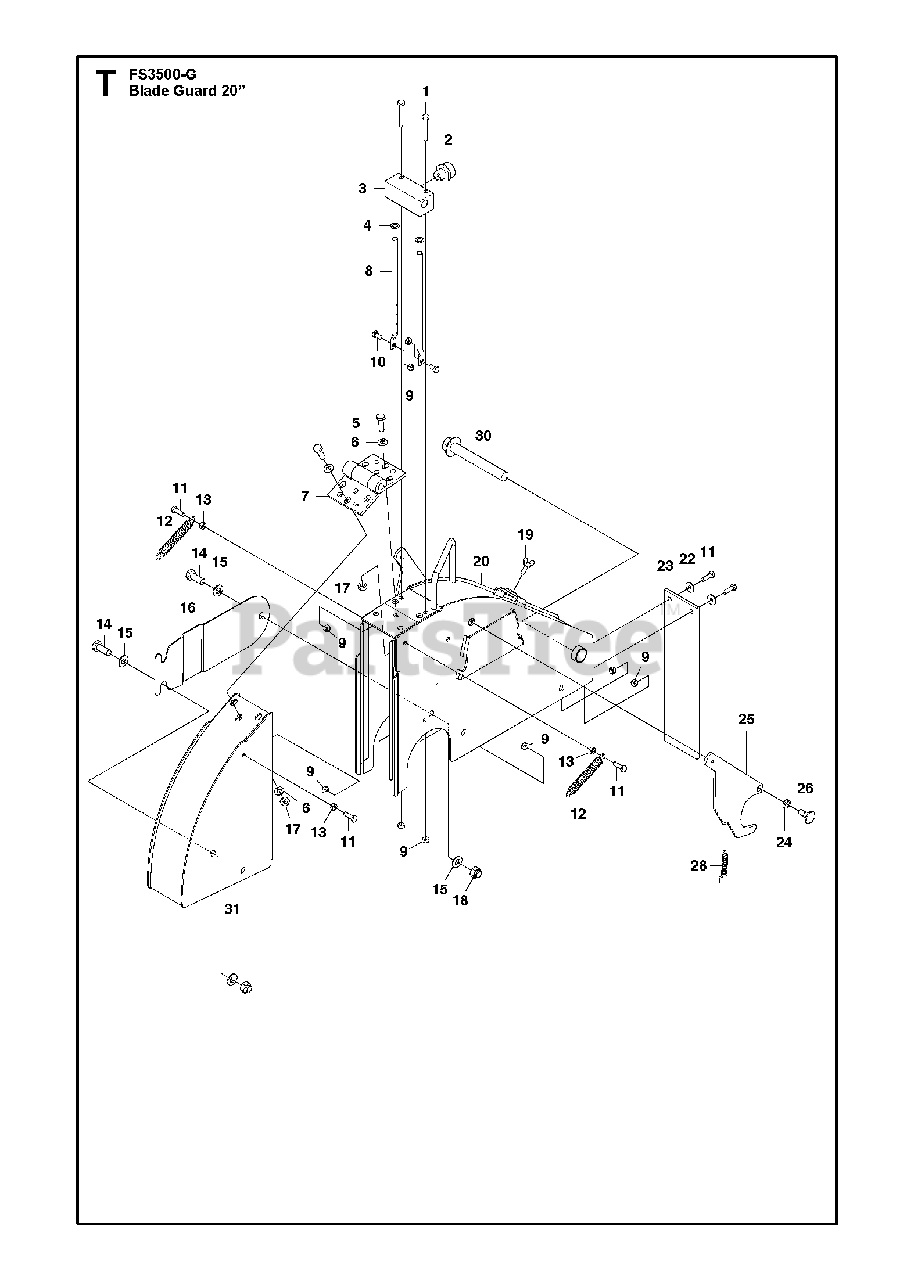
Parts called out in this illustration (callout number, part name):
6	WASHER
9	HEXAGON LOCKING NUT
15	WASHER
17	HEXAGON LOCKING NUT
18	HEXAGON LOCKING NUT
